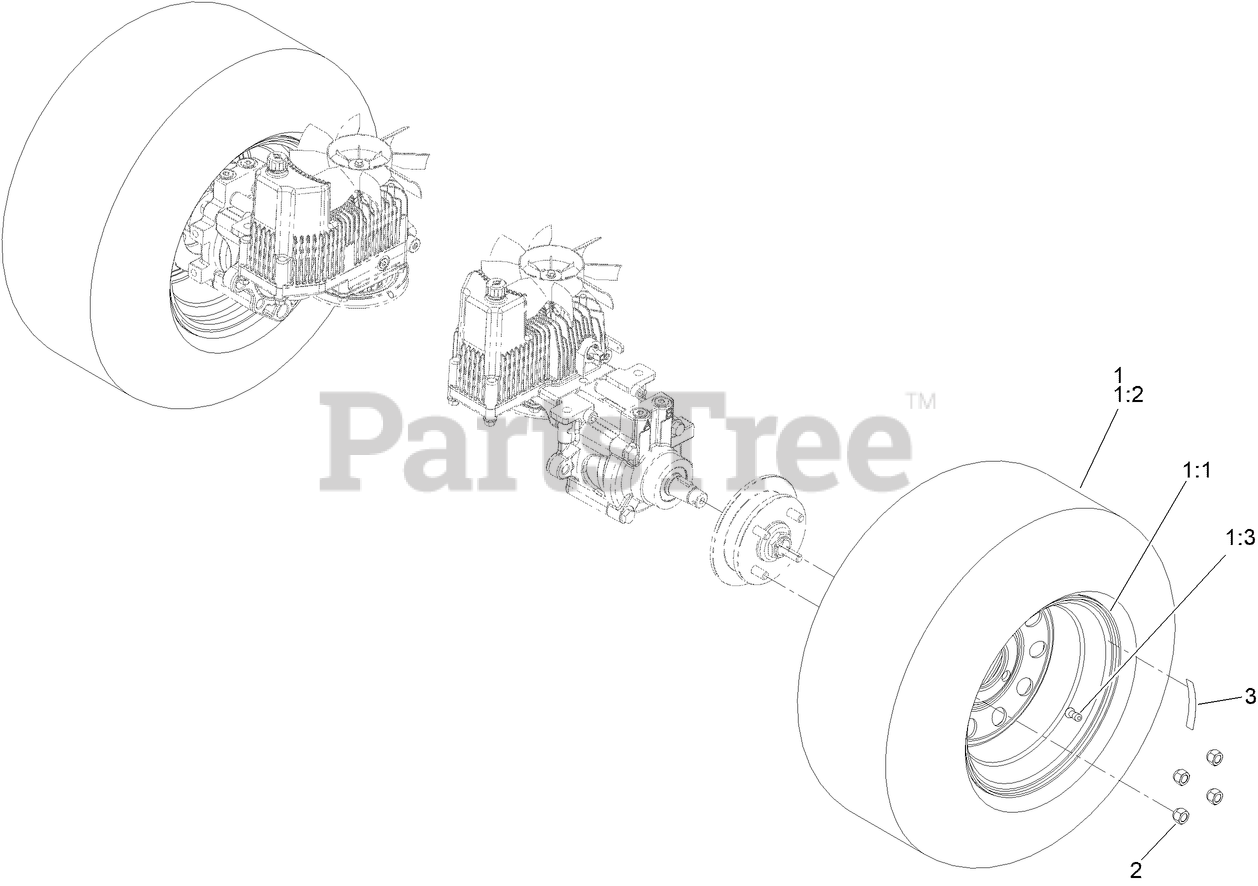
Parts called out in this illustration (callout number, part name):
1	WHEEL AND TIRE ASM
1:2	TIRE, 23 X 9.50-12
2	NUT-LUG
3	DECAL-TORQUE, WHEEL HUB LUG
